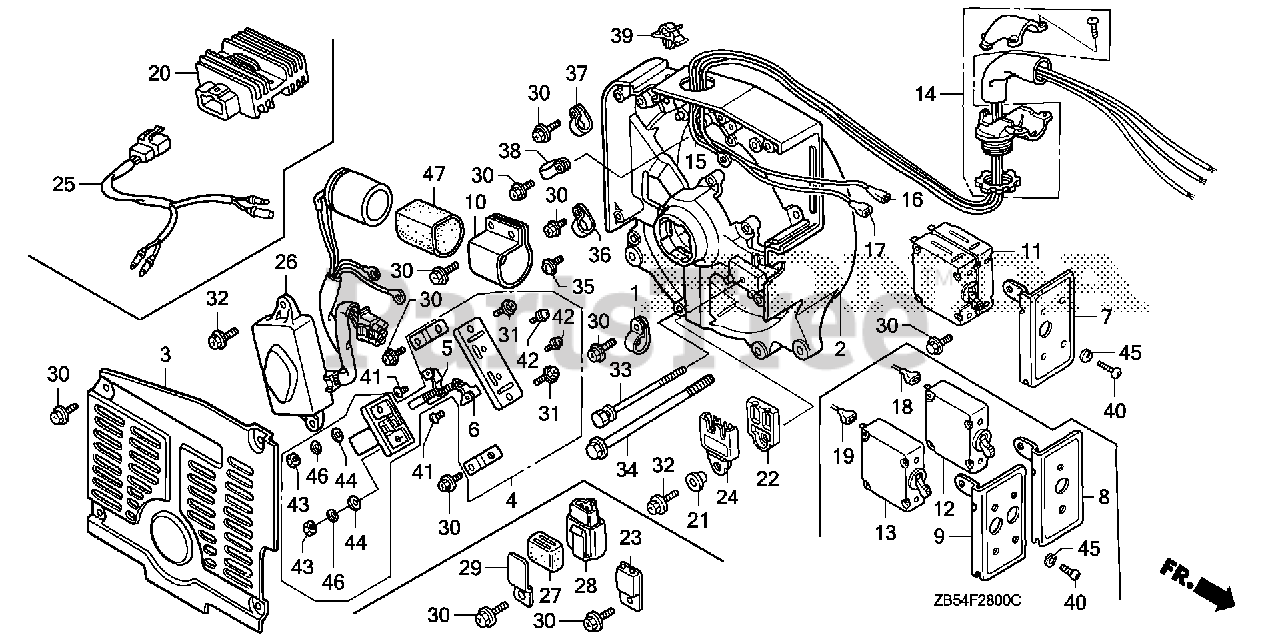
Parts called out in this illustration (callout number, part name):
1	CLAMP F, CABLE
2	HOUSING, RR. (NOT AVAILABLE)
3	COVER, GENERATOR END
4	HOLDER ASSY., BRUSH
7	BRACKET, BREAKER *NH192M* (GENTLY SILVER METALLIC)
10	HOLDER, CONDENSER
11	BREAKER, CIRCUIT (17.5A)
14	FITTING (NOT AVAILABLE)
15	WIRE, GROUND
16	WIRE, BREAKER (RED)
17	WIRE, BREAKER (BROWN)
20	RECTIFIER ASSY., REGULATOR (10A)
23	DIODE, D.C.
25	SUB-WIRE HARNESS ASSY.
26	REGULATOR ASSY., AUTOMATIC VOLTAGE
27	SUSPENSION, TURN SIGNAL RELAY (MITSUBA)
28	RELAY, CONTROL
29	BRACKET, RELAY
30	SCREW, TAPPING (5X12)
31	SCREW, TAPPING (5X14)
32	SCREW, TAPPING (5X14)
33	BOLT-WASHER (5X155)
34	BOLT, FLANGE (8X160)
35	SCREW, PAN (5X12)
37	CLIP (10.7MM)
39	CLIP, CORD
40	SCREW, PAN (3X6)
41	SCREW, PAN (4X8)
42	SCREW-WASHER (4X16)
43	NUT, HEX. (4MM)
44	WASHER, PLAIN (4MM)
45	WASHER, SPRING (3MM)
46	WASHER, SPRING (4MM)
